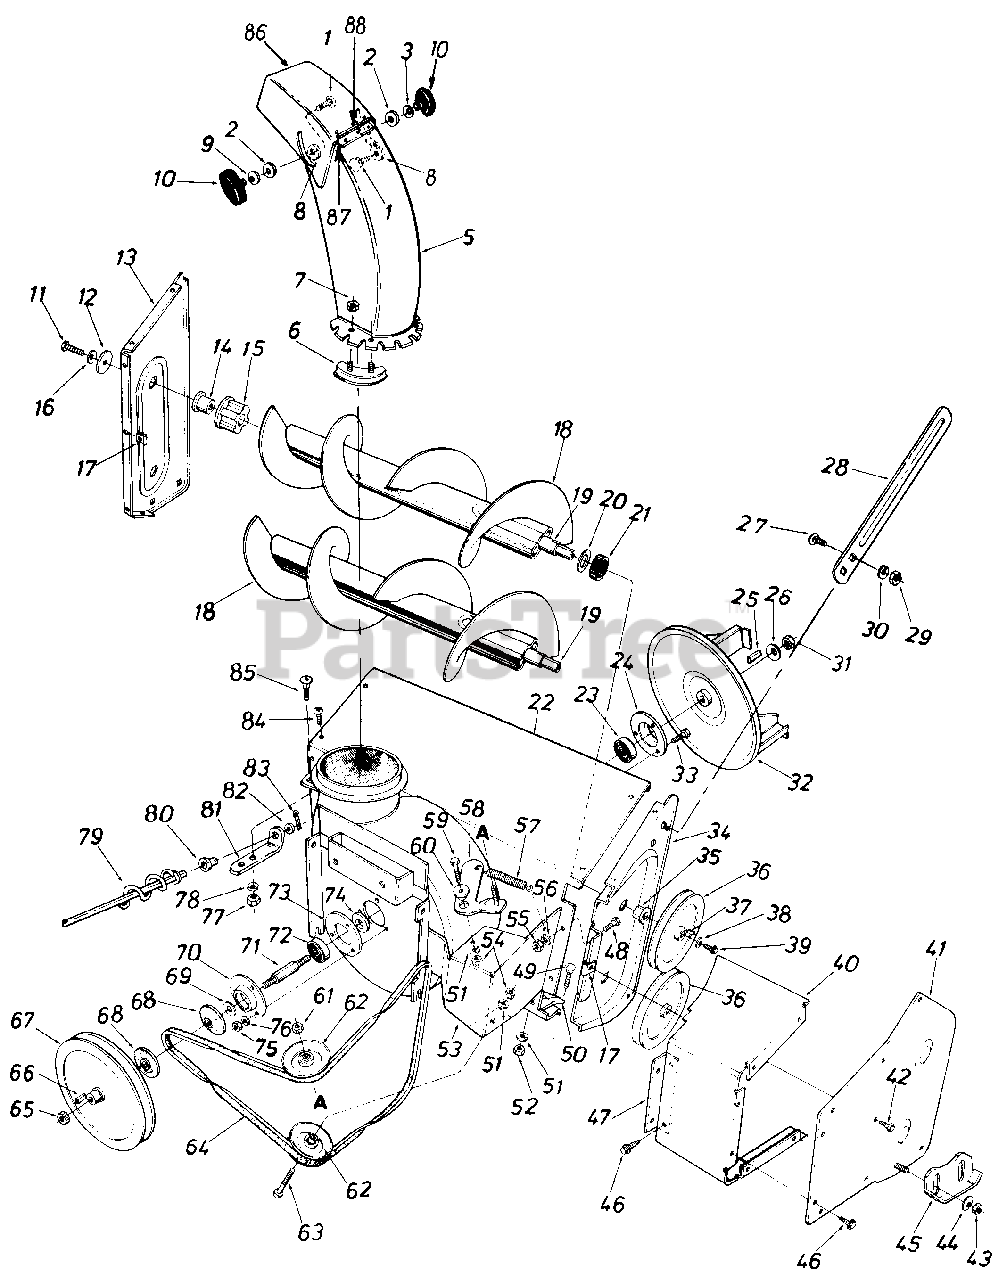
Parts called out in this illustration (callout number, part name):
1	Carriage Bolt 5/16-18 x 1.0" Lg.
2	Fl-Wash. .344" I.D. x 1.125" O.D.
3	Bell-Wash. .345" I.D. x .88" O.D.
5	Blower Chute Ass'y.
6	Chute Flange Keeper Ass'y.
7	Hex Patch L-Nut 1/4-20 Thd.
8	Fl-Wash 531 I.D. x 1.25" 0.D.
9	Bell-Wash. .345" I.D. x .88" O.D.
10	Knob Handle Ass'y.
11	Hex Bolt 5/16-18 x 1.0" Lg. (Grade 5)
12	Fl-Wash. .32" I.D.
13	Spiral Housing Plate L.H.
14	Shaft Pin 1.0" O.D. x .94
15	Tubing Support Brg.
16	Bell-Wash. .345" I.D. x .88" O.D.
17	Speed Clip 1/4-20
18	Auger Ass'y. 22" x 6.0" Dia.
20	Fl-Wash. .760" I.D. x 1.75" 0. D.
21	Spacer 1.25" I.D. x 1.50" O.D x .58" Thk.
22	22" Spiral Housing Ass'y.
23	Ball-Brg. .787" I.D. x 1.85" O.D. x .551
24	Bearing Housing 1.85" I.D.
25	Sq. Key 3/16 x 1.50" Lg.
26	Bell-Wash. .630" I.D. x 1.25" O.D.
27	Carriage Bolt 5/16-18 x .62" Lg.
28	Guide Blade
29	Hex Nut 5/16-18 Thd.
30	L-Wash. 5/16" I.D.
31	Hex Jam Nut 5/8-18 Thd.
32	11" Dia. Blower Fan Ass'y.
33	Hex Bolt 5/16-18 x 1.00" Lg.
34	Spiral Housing Plate R.H.
35	Hex Flange Brg. .751" I.D.
36	3/8" V-Pulley 5/8" I.D. x 5.5" O.D.
37	Sq. Key 3116" X .75" Lg.
38	Bell-Wash. .265" I.D. x .75" O.D.
39	Hex Bolt 1/4-20 x .62" Lg.
40	Belt Cover Top
41	Belt Cover Side Ass'y.
42	Hex Bolt 3/8-16 x .75" Lg.
43	Hex Jam Nut 3/8-16 Thd.
44	Bell-Wash. .400" I.D. x .88" O.D.
47	Support Bracket
48	Hex Bolt 5/16-18 x .50" Lg.
49	Carriage Bolt 5/16-18 x .62" Lg.
50	Scraper Bar Kit 22"
51	Bell-Wash. .345" I.D. x .88" O.D.
52	Hex Nut 5/16-18 Thd.
54	Hex Nut 3/8-24 Thd.
55	Hex Nut 5/16-18 Thd.
56	L-Wash. 5/16" I.D.
57	Extension Spring .620" O.D. x3" Lg.
58	Idler Bracket Ass'y.
59	Hex Bolt 3/8-24 x .75" Lg.
60	Shld. Spacer .625" I.D.
61	Hex Ins. L-Nut 3/8-24 Thd.
62	"V"-Idler 2.62" O.D.
63	Hex Bolt 3/8-24 x 1.25" Lg.
64	V-Belt 3V x 58" Lg.
65	Hex Cent. L-Nut 5/8-18 Thd.
66	Sq. Key 3/16 x .75" Lg.
67	518" "V"-Pulley .628" I.D. x 7.50" O.D.
68	3/8" "V"-Pulley Half .625" I.D. x 2.25" O.D.
69	Fl-Wash. .635" I.D. x 1.12" 0. D.
70	Open Brg. Housing Ass'y.
71	Fan Spindle
72	Ball Brg. .787" I.D. x 1.85" O.D.
73	Open Brg. Housing 1.85" I.D.
74	Spacer .790" I.D. x 1.0" O.D.
75	Hex Nut 5/16-18 Thd.
76	L-Wash. 5/16" I.D.
77	Hex Nut 5/16-18 Thd.
78	L-Wash. 5/16" I.D.
79	Chute Crank Ass'y. R.H. 39.0" Lg.
80	Plastic Bushing .380" I.D.
82	Fl-Wash. .385" I.D. x .62" O.D.
83	Cotter Pin 3/32" Dia. x .75" Lg.
84	Truss Mach. Scr. 1/4-20 X .50" Lg.
85	Carr. Bolt 5/16-18 x .75" Lg.
86	Upper Chute
87	Push Nut
88	Chute Hinge Pin
